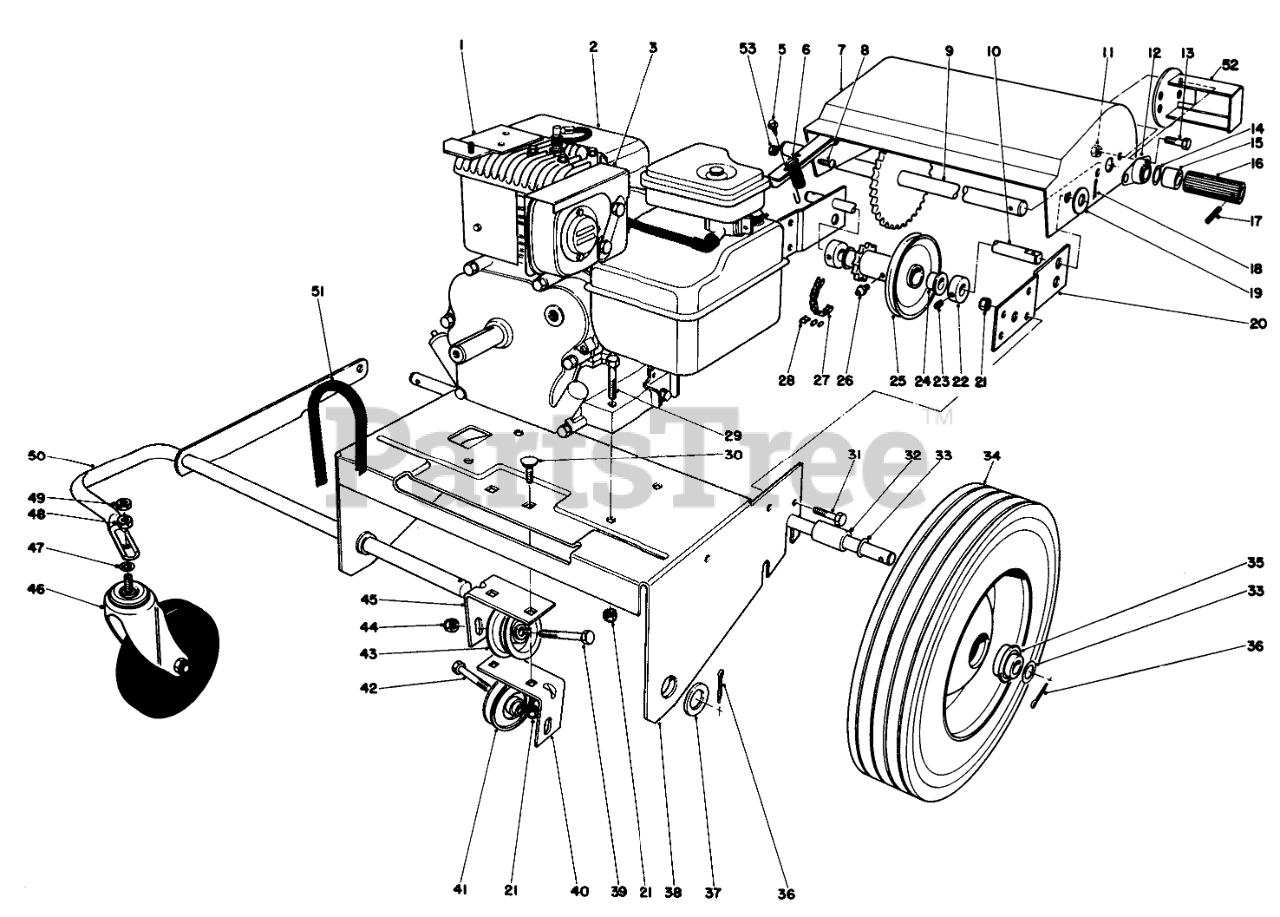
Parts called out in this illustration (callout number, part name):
1	MTG BRKT WA B
2	Engine
3	HEAT SHIELD
5	SCREW-HH
6	SPRING-TRACTION
7	GUARD WA
8	10-24 X 3/8 PAN HD SC
9	SHAFT-WHEEL, FRICTION
10	SHAFT-IDLER
11	NUT-LOCK, NI
12	BEARING-MOUNT, FLANGE
13	SCREW-HH
14	WASHER
15	SPACER
16	WHEEL-FRICTION
17	PIN-ROLL, SLOTTED
18	PIN-COTTER
19	WASHER-FLAT
20	Bracket Mounting
21	NUT-LOCK, CONE
22	Set Screw Collar (Incl. Ref. #23)
23	SCREW-SET, HSH
24	BUSHING-FLANGE
25	Idler Assembly (Incl. Ref. #24 & 26)
26	FITTING-GREASE
27	Traction Chain (Incl. Ref. #28)
28	LINK-CONNECTING, NO. 35
29	SCREW-HH
30	SCREW-CARR
31	SCREW-HH
32	SPACER-AXLE
33	WASHER
34	Wheel (Incl. Ref. #35)
35	BEARING
36	PIN-COTTER
37	WASHER-FLAT
38	Engine Plate
39	SCREW-HH
40	Bracket-Idler Mount L.H.
41	PULLEY-IDLER
42	SCREW-HH
43	PULLEY-IDLER
44	NUT-LOCK, CONE
45	Bracket-Idler Mount R.H.
46	CASTER
47	WASHER-LOCK/INT
48	NUT-HH
49	1/2-13 CONELOCK NUT
50	Front Wheel Support
51	BELT-V
52	Guard
53	NUT-KEPS
